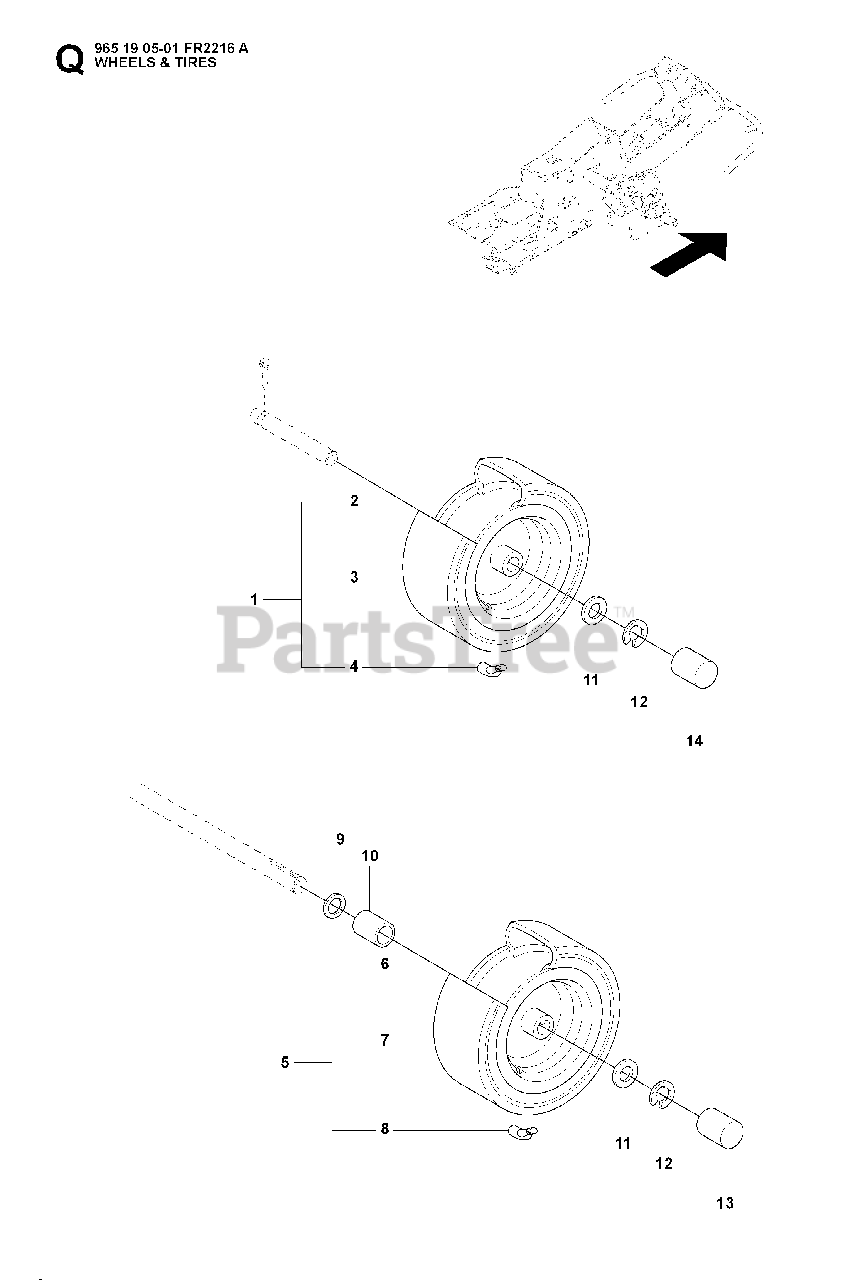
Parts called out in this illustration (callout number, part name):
6	RP RIM
10	SPACE SLEEVE
12	RETAINING RING
